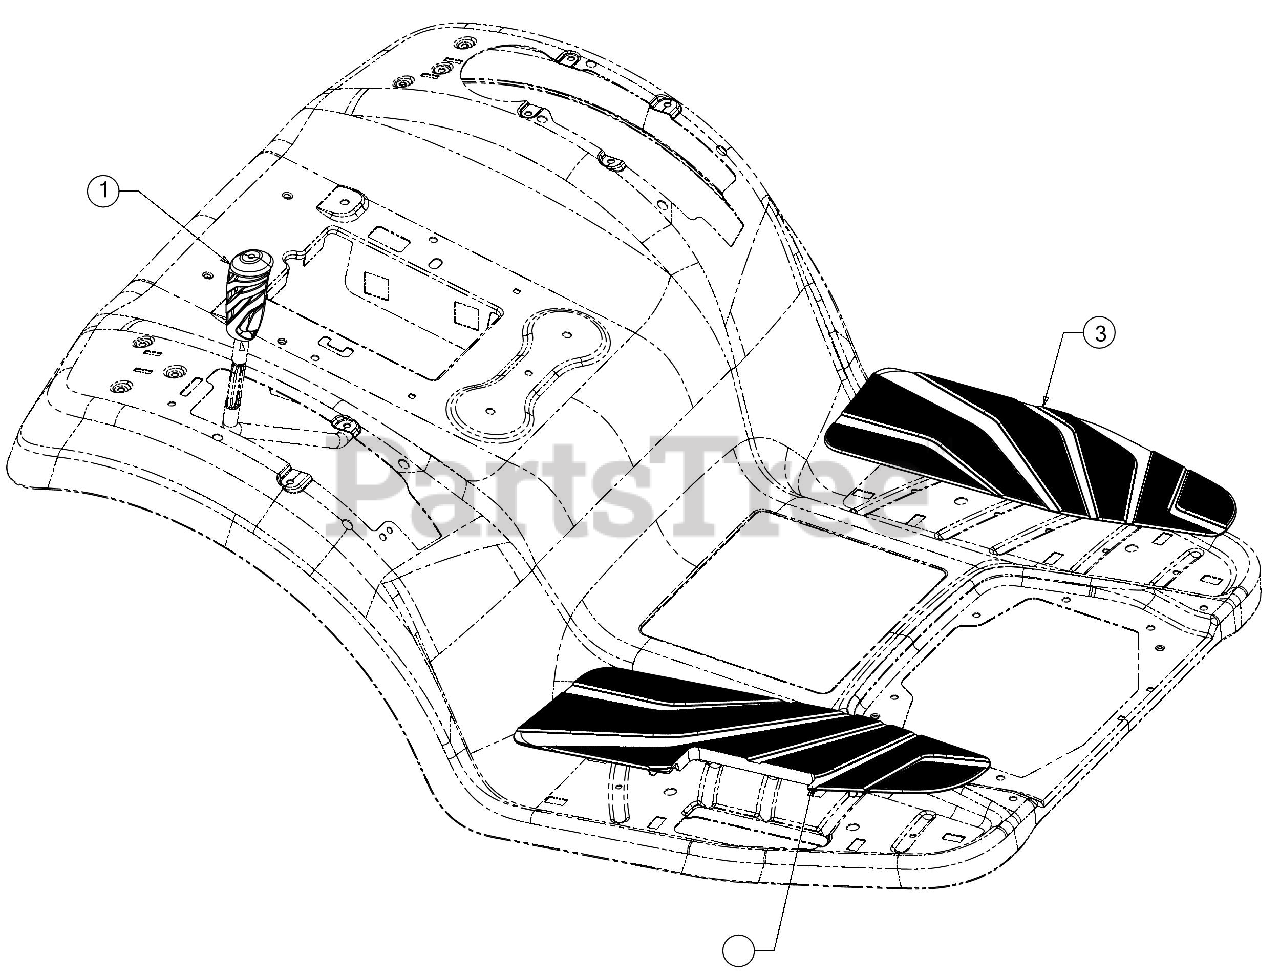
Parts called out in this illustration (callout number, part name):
1	LIFT HANDLE GRIP .542 ID
3	FOOTPAD-LEFT
4	FOOTPAD-RIGHT
